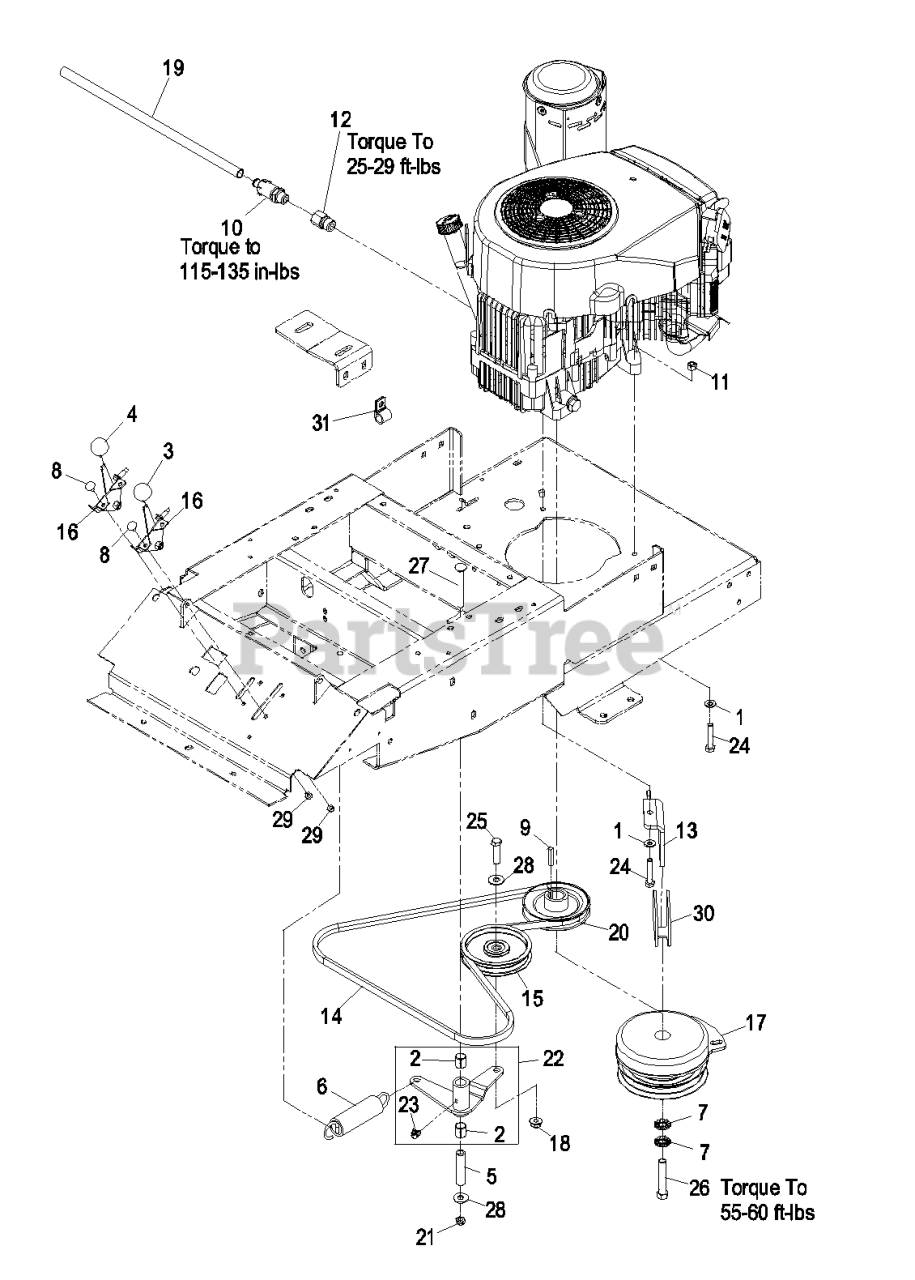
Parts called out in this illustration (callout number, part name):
1	WASHER-SPRING
2	SLEEVE-BEARING
3	KNOB-BALL
4	KNOB-BALL, BLACK
5	BUSHING-PIVOT, IDLER
6	SPRING-EXTENSION
7	WASHER-SPRING
8	BOLT-CARR
9	KEY-SQUARE
10	VALVE-DRAIN, OIL
11	NUT-LOCK, NI
12	ADAPTER
13	ROTATION-STOP, CLUTCH
16	THROTTLE CONTROL ASM
18	NUT-HF, NI
19	TUBE-DRAIN, OIL
22	IDLER HYDRO ASM
23	FITTING-GREASE, 90 DEG
24	SCREW-HH
25	SCREW-HH
26	SCREW-HH
27	SCREW-CARR
28	WASHER-FLAT
29	NUT-LOCK, NI
31	CLIP-LOOM
